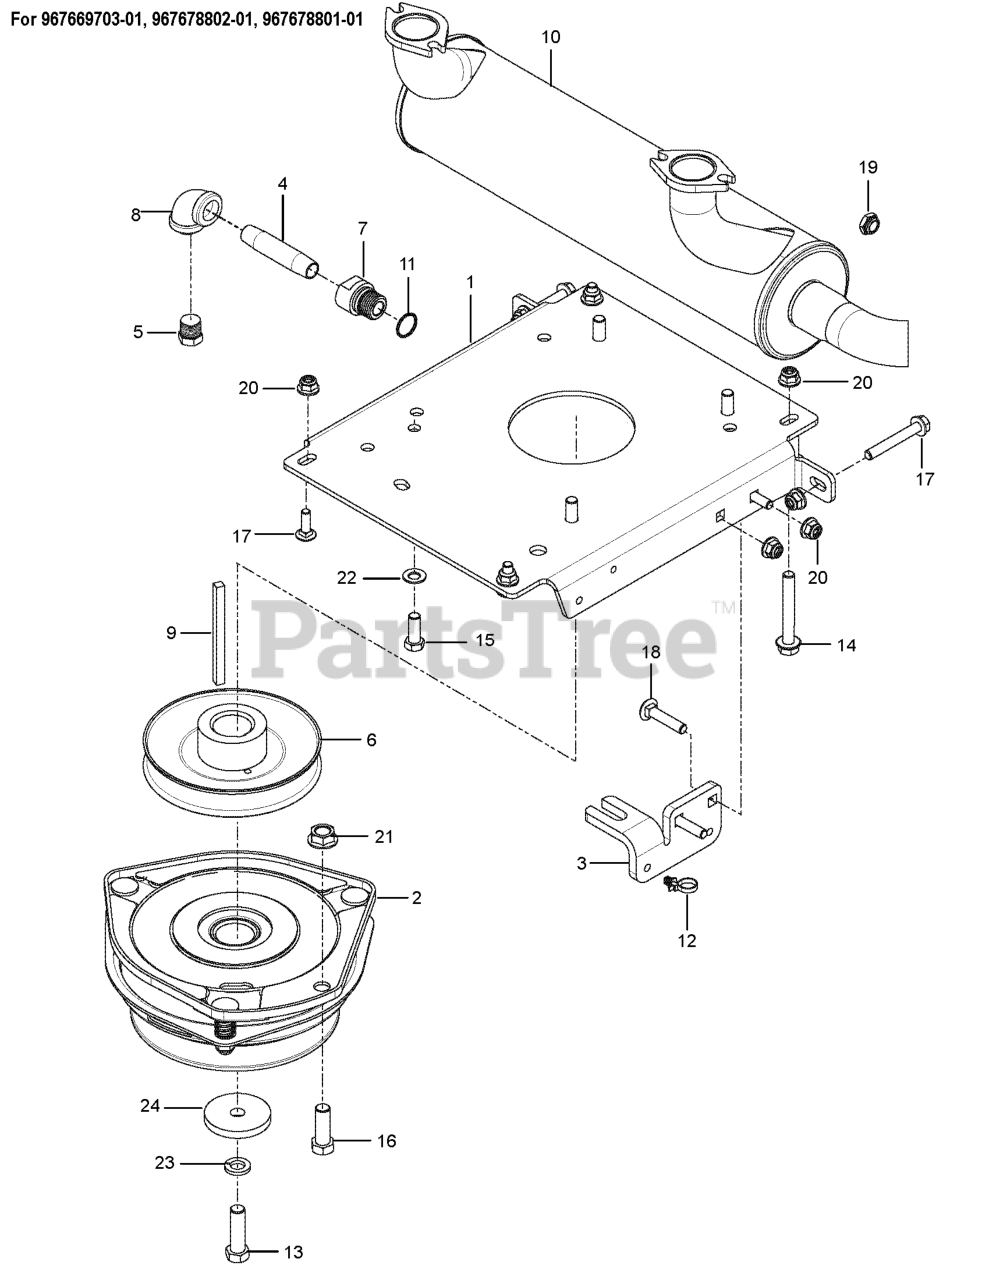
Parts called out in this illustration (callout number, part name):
1	PLATE.PNT.ENGINE.PZ/PZT.EDIP
2	CLUTCH, GT3.5
3	STOP, CLUTCH, OGURA
4	PIPE NIPPLE 3/8 X 3
5	PLUG, DRAIN 3/8 NPTF
6	PULLEY, ENGINE
7	ADAPTER, OIL DRAIN
8	90 DEG.ELBOW 3/8NPT
9	KEY, 1/4 SQ X 3.5
10	MUFFLER, 34HP KAW FX921V-1000V
12	TIE WRAP, 8-3/8", W/CLIP
13	CLUTCH BOLT7/16-20X1.5GR5.96HR
14	HHFS 5/16-18 X 2.25 GD 5
15	HCS 3/8-16X1.GRD.5.ZD
16	BOLT FIN HEX 7/16-14 X 1
17	RHSNB 5/16C X 1
18	RHSNB 5/16-18 X 1-1/2 GR 5 ZD
19	JAM NUT 1/4C (2 2 PW01)
20	5/16-18 NYLOC FLANGE NUT
21	NUT 7/16C WHIZ
22	WASHER, 3/8 DISC SPRING SPEC
23	WASHER 7/16 LOCK
24	BLADE WASHER
